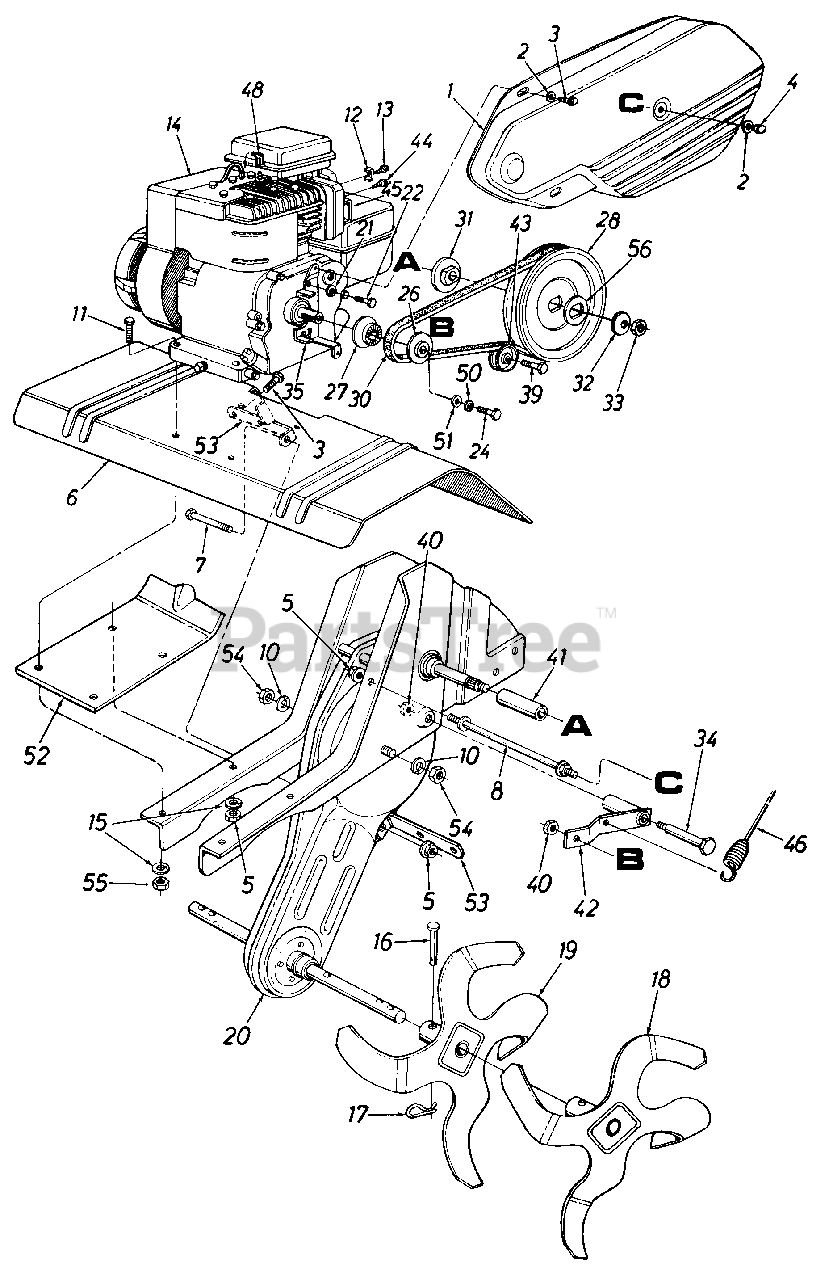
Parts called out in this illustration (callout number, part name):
2	Fl-Wash. .266" I.D. x .625" O.D.
3	Hex Wash. Hd. TT-Tap Scr. 1/4-20 x .5" Lg.
4	Hex L-Stop Nut 1/4-28 Thd.
5	Hex Flange Top L-Nut 5/16-18 Thd. (Gr. 5)
8	Belt Cover Bolt
10	L-Wash. 7/16" I.D.
11	Hex Bolt 5/16-18 x 1.75" Lg.
12	Casing Clamp
13	Hex Sems Scr. #10-32 x .62" Lg.
14	Engine
15	Spec. L-Nut 5/16" I.D.
16	Clevis Pin .375" Dia. x 1.75" Lg.
17	Internal Cotter Pin
20	Chain Case Ass'y. Comp.
21	L-Wash. 5/16" I.D.
22	Hex Bolt 5/16-24 x .5" Lg.
24	Hex Bolt 3/8-24 x 1.25" Lg.
26	Outer Engine Pulley Half
27	Inner Engine Pulley Half
28	Fl-Pulley 6" Dia.
30	"V"-Belt
31	Pulley Mounting Adapter
32	Bell-Wash. .535" I.D. x 1.5" O.D.
33	Hex Jam Nut 1/2-20 Thd. (Gr. 5)
34	Shld. Bolt .498" Dia. x 1.45" Lg.
39	Hex Cap Bolt 3/8-16 x 1.25" Lg.
40	Hex Cent. Jam Nut 3/8-16 Thd.
41	Spacer .64" I.D. x 2.4" Lg.
42	Tine Idler Brkt. Ass'y.
43	Fl-Idler 2" O.D.
44	Hex Self-Tap Scr. #8-32 x .38" Lg.
45	Muffler Deflector
46	Clutch Control Cable
48	Spark Plug Boot
50	L-Wash. 3/8" I.D.
51	Fl-Wash. 3/8" I.D. x 1" O.D.
54	Hex Nut 7/16-20 Thd.
55	Hex Nut 5/16-18 Thd.
56	Bearing Retainer Washer
